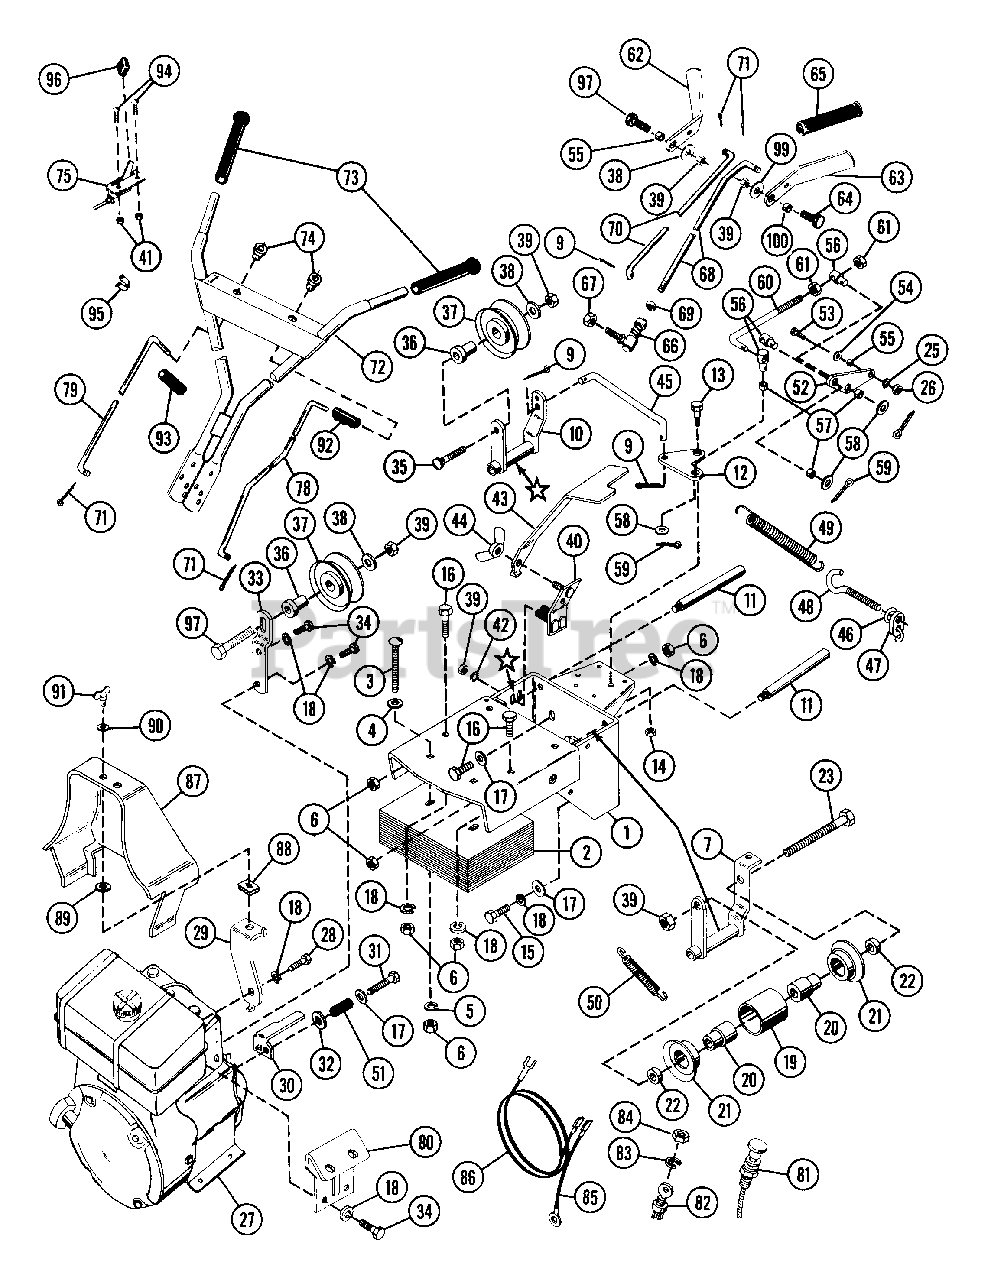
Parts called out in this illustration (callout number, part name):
1	FRAME
2	WEIGHT WAFER
3	BLT-RDHDSQNK .38-16X1.75 PL
4	WSHR-FL-STL .630X1.005X.062 PL
5	WSHR-LK .375X.094 MED PL
6	NUT-LK-FLG .375-16 PL
7	IDLER ARM
8	WSHR-LK-EXT .375X.050
9	PIN-COTR .12X1.0 PL
10	REVERSE IDLER ARM
11	IDLER PIN
12	PIVOT LEVER
13	BLT.SHLDR .38-16 X 1.25
14	NUT-LK-CTR .375-16 GR A PL
15	BLT-HEX .38-16X1.00 PL
16	BLT-HEX .38-16X1.25 PL GR 2
17	WSHR-FL-STL.406X.812X.065PL
18	WSHR-LK .375X.115 HVY PL
20	BEARING SPACER
22	BSHG, SPCR.500X.750X.321 PM
23	BLT-HEX .31-18X4.00 PL GR2
24	WSHR-FL-STL .323X.625X.062 PL
25	WSHR-LK .312X.097 PL HVY
26	NUT-LK .312-18 GR A PL
27	ENGINE
28	BLT-HEX .38-16X.63 PL GR2
29	BELT COVER BRACKET
30	BELT FINGER
31	BLT-HEX .38-16X2.00 PL GR2
32	WSHR-FL-STL .406X1.125X.125 PL
33	REVERSE IDLER BRACKET
34	BLT-HEX .38-16X.75 PL GR2
35	BLT-RDHDSQNK .31-18X1.25 SHTPL
36	SPCR, BRG .315X.50X.688X.281
37	IDLER
38	WSHR-FL-STL .38X.875X.083 PL
39	NUT-LK .312-18 GR A PL
40	BELT FINGER BRACKET
41	NUT-KEPS 10-24 PL
42	WSHR-FL-STL .323X.625X.062 PL
43	BELT FINGER
44	NUT-WING W/INSERT .312 - 18
45	CROSS LINK
46	LINK-CLUTCH
47	RETAINING NUT
48	EYE BOLT
49	SG-TENS .105X.812X3.88 WLD 15
50	SG-TENS .063X.44X2.81 WLD 18
51	SG-COMP .125X.68X1.62
53	BLT-HEX .31-18X.88 PL GR2
54	WSHR-FL-STL .390X.750X.125 PL
55	SPACER BUSHING .5 X .32 X .21
56	UNIVERSAL ROD ADAPTER
57	SPACER .63 X .50 X .18
58	WSHR-FL-STL .505X.880X.072 PL
59	PIN-COTR .15 X 1.0 PL
61	NUT-JAM .375-16 PL
62	DRIVE CLUTCH HANDLE
63	TILLER CLUTCH HANDLE
64	BLT-HEX .31-18X.75 PL GR2
66	SNAP IN BALL JOINT
67	NUT-LK-CTR .312-24 PL
68	TILLER CLUTCH ROD
69	NUT-HEX .312-24 PL
70	DRIVE CLUTCH ROD
71	PIN-COTR .09X.75 PL
72	HANDLEBAR
73	HANDLEGRIP
74	SNAP BUSHING
75	THROTTLE CONTROL
76	CABLE CLAMP NON SKID
77	SCR-MCH 8-32X.50 SLTR PL
78	CLUTCH ROD
79	POSITION ROD
80	CONTROL BRACKET
81	CHOKE CONTROL
82	SWITCH & KEY SET ASSEMBLY
83	WSHR-LK-INT .625X.045 PL
84	NUT .625-32 ALUM
85	SHORTING WIRE
86	SHORTING WIRE
87	BELT GUARD
88	NUT-SPEED 1/4 TURN SOUTHCO
89	NUT-RETNR
90	WSHR-FL-STL .250X.562X.049 PL
91	SCR-WING .25 TURN SOUTHCO
92	GRIP
93	GRIP
94	SCR-MCH 10-24X.50 SLRH BL
95	CABLE RETAINER
96	KNOB, CONTROL-THROTTLE
97	BLT-HEX .31-18X1.25 PL GR2
98	WSHR-LOCK EXT 8X.020 MED
99	WSHR-FL-STL .344X1.375X.075 PL
100	SPACER
